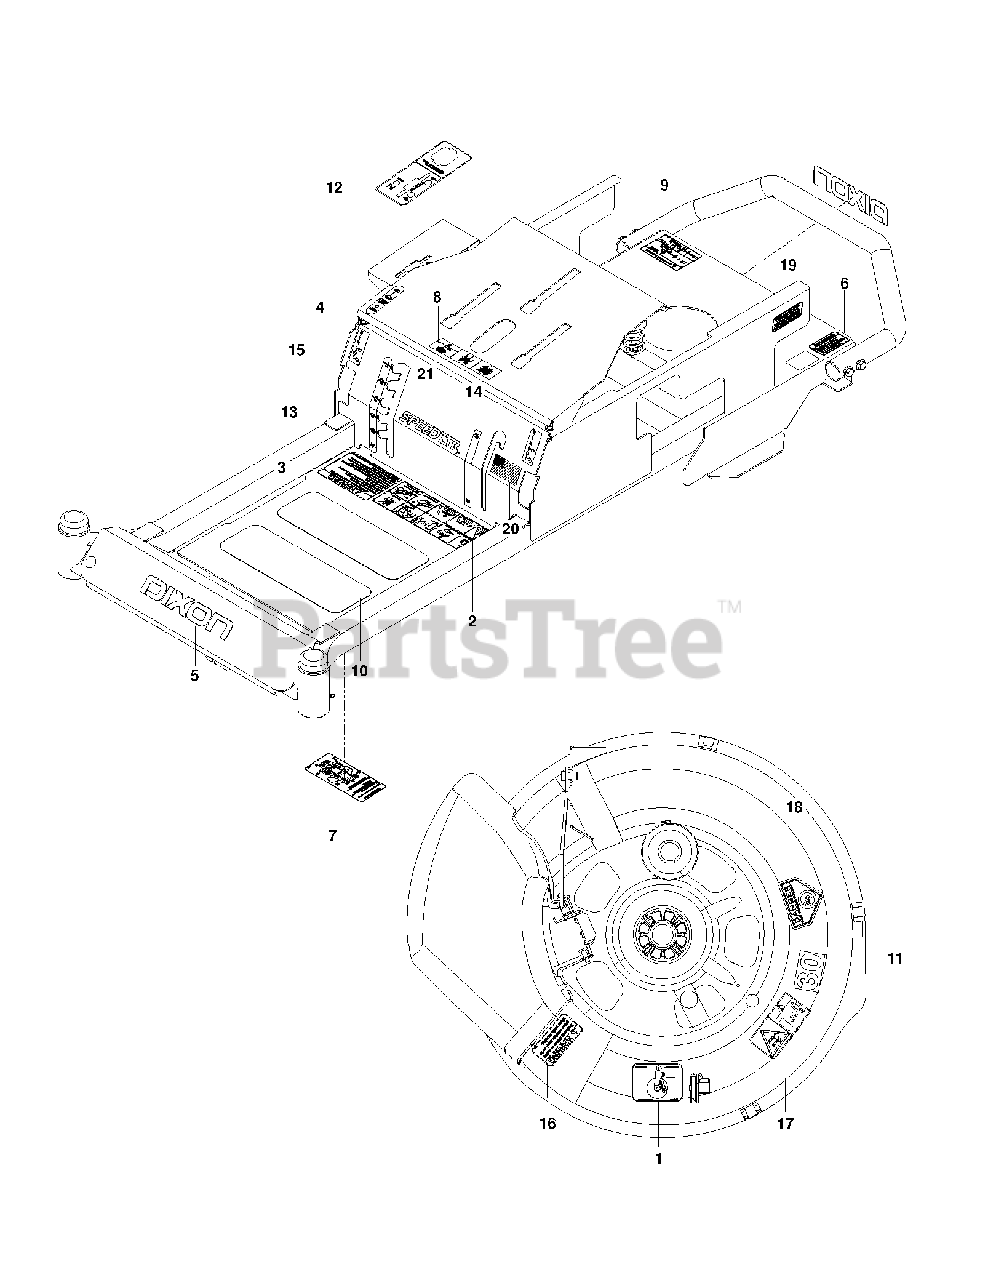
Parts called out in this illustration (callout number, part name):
1	DECAL, BELT ROUTING
2	DECAL, SAFETY WARNING
3	DECAL, WARNING
4	DECAL, PARK BRAKE
6	DECAL, PROP. 65
7	DECAL, SERVICE
9	DECAL, DO NOT MOUNT
10	ANTI-SKID PAD
11	DECAL, 30, WHITE
12	DECAL, CONTROL PANEL
13	DECAL, DECK HEIGHT
14	DECAL, BLADE ENGAGEMENT
15	DECAL, MOTION CONTROL
16	DECAL, CAUTION
17	DECAL, EURO SEVERING
18	DECAL, CPSC
19	DECAL, WARNING SPARK ARRESTOR
20	DECAL, FLAG
21	DECAL, SPEEDZTR 6.5"
